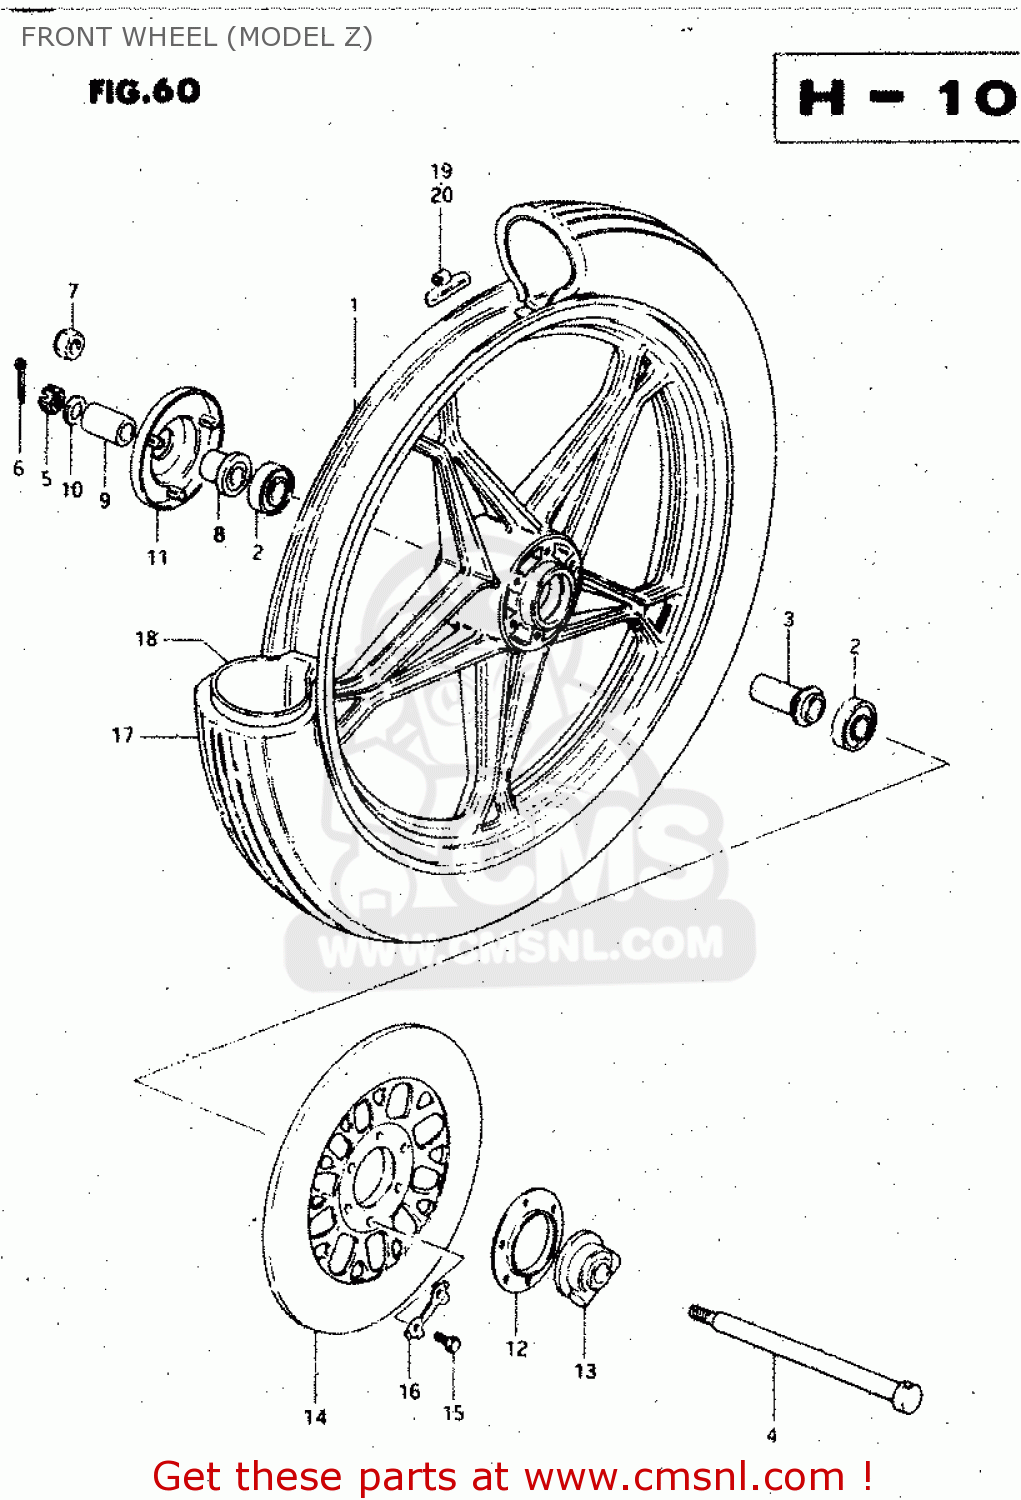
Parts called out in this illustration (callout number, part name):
1	CASTING WHEEL,FRONT 1.85
2	BEARING
3	SPACER,FR HUB BEARING
4	AXLE,FRONT
5	NUT 12MM
6	COTTER PIN
7	NUT
8	SPACER,FR HUB BEARING,R
9	SPACER(15X22X30)
10	WASHER
11	COVER,FR HUB,R
12	DUST SEAL,SPEEDOMETER GEAR BOX
13	BOX ASSEMBLY,SPEEDOMETER GEAR
14	DISC,FR BRAKE
15	BOLT(8X25)
16	WASHER
17	TIRE,FRONT
18	TUBE,INNER
19	BALANCER,WHEEL
20	BALANCER,WHEEL
